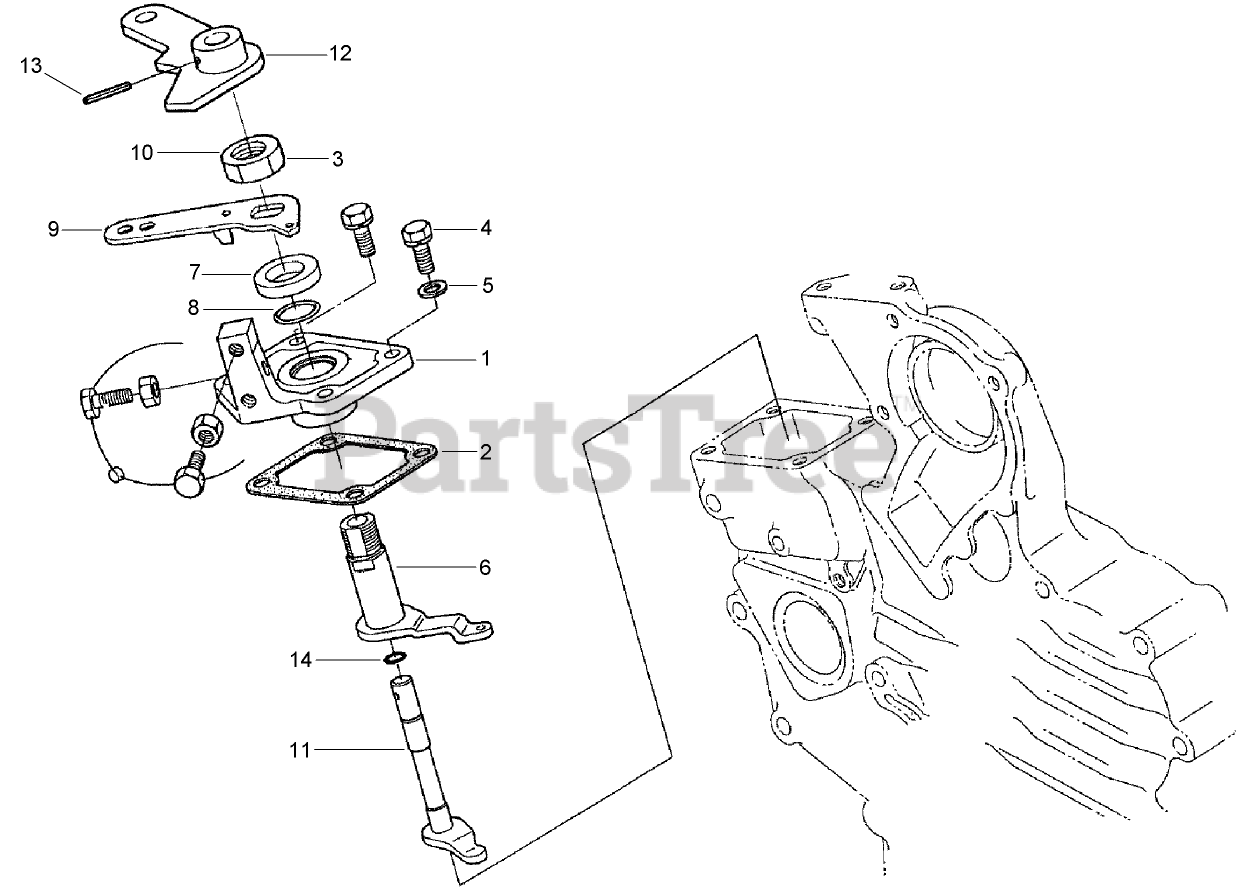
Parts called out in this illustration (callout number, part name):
1	PLATE-CONTROL, SPEED
2	GASKET
4	BOLT
5	GASKET
6	LEVER-GOVERNOR
7	COLLAR
8	O-RING
9	LEVER-CONTROL, SPEED
10	NUT-CONTROL, SPEED
11	SHAFT-LEVER
12	LEVER-STOP, ENGINE
13	PIN-SPRING
14	O-RING
